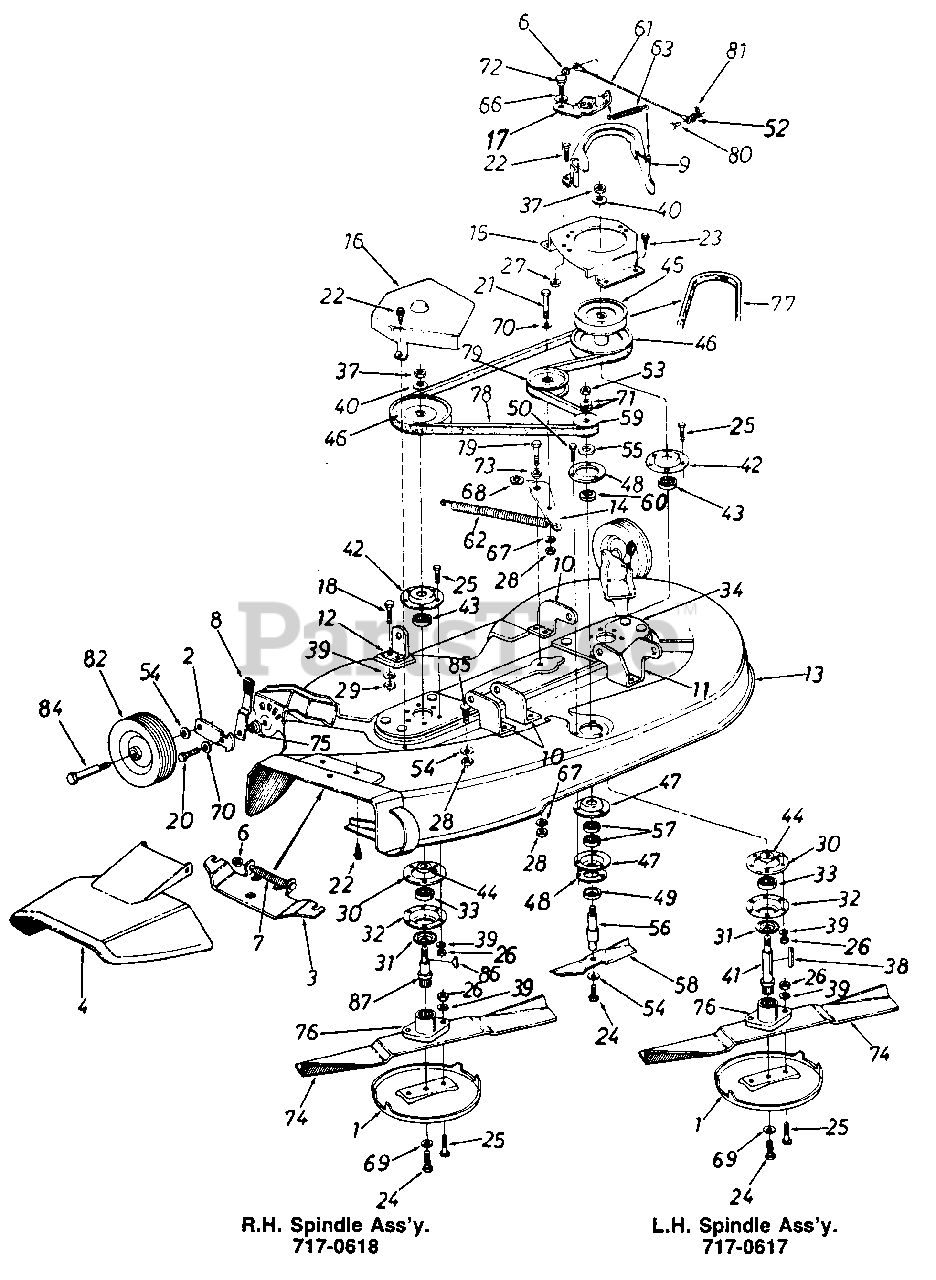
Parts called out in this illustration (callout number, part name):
1	Anti-Scalp Plate
2	Bar-Wheel Pivot
3	Adapter Plate
4	Chute Cover Ass'y.
6	Cap Speed Nut 1/4" Rod
7	Torsion Spring
8	Spring Lever Ass'y.
9	Belt Guard
12	Deck Hanger Bracket
13	44" Deck Ass y
14	Idler Bracket
15	Pulley Cover L.H.
18	Hex Bolt 5/16-18 x .75" Lg.
19	Hex Bolt 3/8-24 x 1.00" Lg.
20	Hex Bolt 3/8-24 x 1.25" Lg.
21	Hex Bolt 3/8-24 x 1.50" Lg.
22	Hex Wash. S-Tapp Scr. 1/4-20 x .50
23	Hex Wash. Hd. Tapp Scr. 5/16-18 x .75" Lg.
24	Hex Cent. L-Bolt 3/8-24 x .88" Lg.
25	Hex Bolt Special 5/16-24 x 1.0" Lg.
26	Hex Nut 5/16-24 Thd.
27	Hex Cent. L-Nut 5/16-18 Thd.
28	Hex Nut 3/8-24 Thd.
29	Hex Nut 5/16-18 Thd.
30	Reinforcement Plate
31	Bearing Shield
32	Open Brg. Housing 1.85 I.D.
33	Ball Brg. .787" I.D. x 1.85" O.D. x .551
34	Spindle Mounting Plate Ass'y.
37	Hex Jam Nut 5/8-18 Thd.
38	Sq. Key 3/16" x 2.25" Lg.
39	L-Wash. 5/16" I.D.
40	Bell-Wash. .630" I.D. x 1.25" 0. D.
41	44" Deck Blade Spindle
42	Bearing Housing 1.85" I.D.
43	Ball Brg. .787" I.D. x 1.85" O.D. x .551
44	Spacer 1.0" O.D. x .790" I.D.
45	5/8 "V"-Pulley .79" I.D. x 5.75" O.D.
46	"V"-Pulley .79" I.D. x 6.50" O.D.
47	Bearing Housing 1-3/8 I.D.
48	Reinforcement Plate
49	Bearing Shield
50	Hex Wash. Hd. B-Tap Scr. 1/4 x.75" Lg.
52	Fl-Wash. .20" I.D. x .62" O.D.
53	Hex Jam Nut 1/2-20 Thd.
54	Bell-Wash. .400" I.D. x .88" O.D.
55	Fl-Wash. .635" I.D. x 1.04" O.D.
56	6.5" Blade Spindle
57	Ball Brg. .62" I.D. x 1.38" O.D. x .44
58	6.5" Blade
59	1/2" "V"-Pulley Half .625" I.D. x 2.25" O.D.
60	Fl-Wash. 518" I.D. x 15/16" O.D.
61	Brake Cable 11.75" Lg.
62	Extension Spring .73" O.D. x 4.31 " Lg.
63	Ext. Spring .50" x 2.51" Lg.
66	Spring Wash. .445" I.D. x .75" O.D.
67	L-Wash. 3/8" I.D.
68	Spring Wash. .625" I.D. x .885" O.D.
69	L-Wash. 3/8" I.D. (Heavy Duty)
70	Bell-Wash. .400" I.D. x 1.13" O.D.
71	Bell-Wash. .505" I.D. x 1.00" O.D.
72	Shld. Bolt .437" Dia. x .180
73	Shld. Spacer .625" I.D.
74	21" Blade
75	Shld. Spacer
76	Blade Adapter
77	"V"-Belt 1/2" X 52.0" Lg.
78	'V"-Belt 1/2" x 74.0" Lg.
79	Fl-Idler w/Flanges 3.50" O.D.
80	Clevis Pin 1/4" Dia. x .53" Lg.
81	Intern. Cotter Pin 5/16" Dia.
82	Deck Wheel 6.0" x 1.38
84	Shld. Bolt 3/8-16 x 1.41
85	Rib Neck Bolt
86	Sq. Key 3/16" x 3/16" x .75" Lg.
87	44" Deck Blade Spindle
